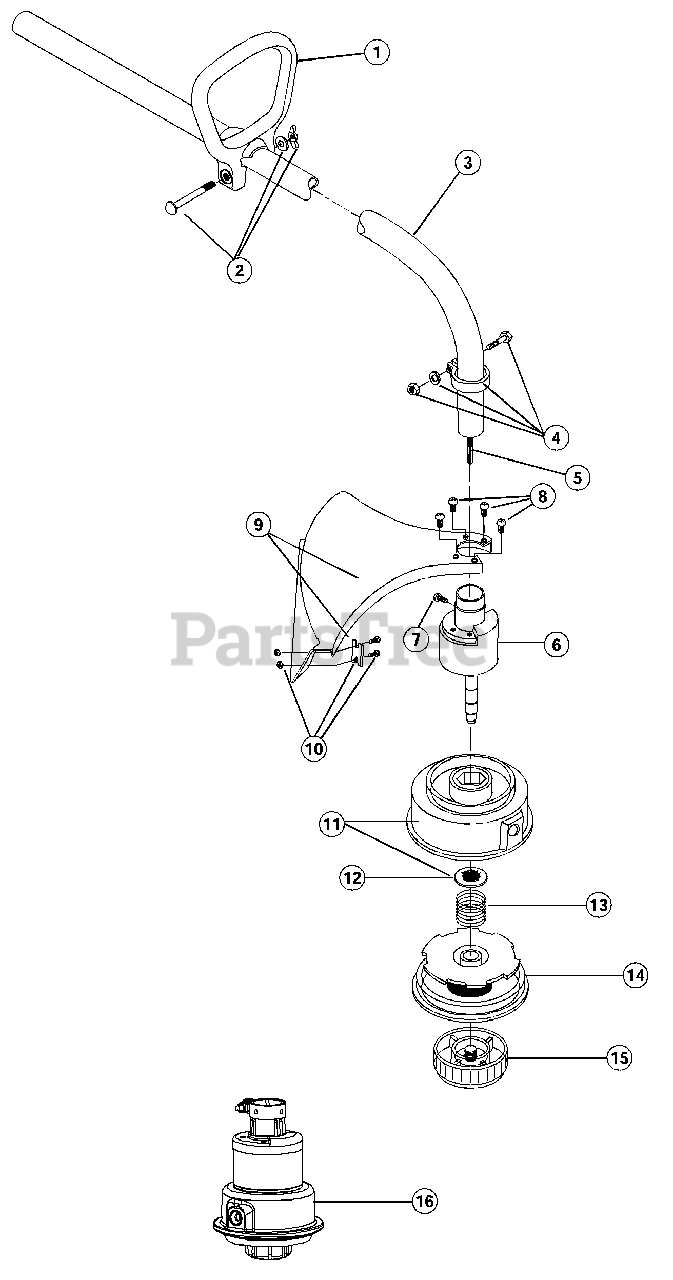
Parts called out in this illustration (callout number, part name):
1	D-Handle Assembly
2	D-Handle Hardware
3	Drive Shaft Housing Assembly
4	Lower Clamp Assembly
5	Flexible Drive Shaft
6	Bushing Housing Assembly w/shaft
7	Anti-Rotation Screw
8	Guard Mounting Screw Assembly
9	Guard and Blade Assembly
10	Blade Assembly
11	Outer Spool and Eyelet Assembly w/ Retainer
12	Retainer
13	Spring
14	Inner Reel
15	Bump Head Knob
16	Complete Cutting Head Assembly
